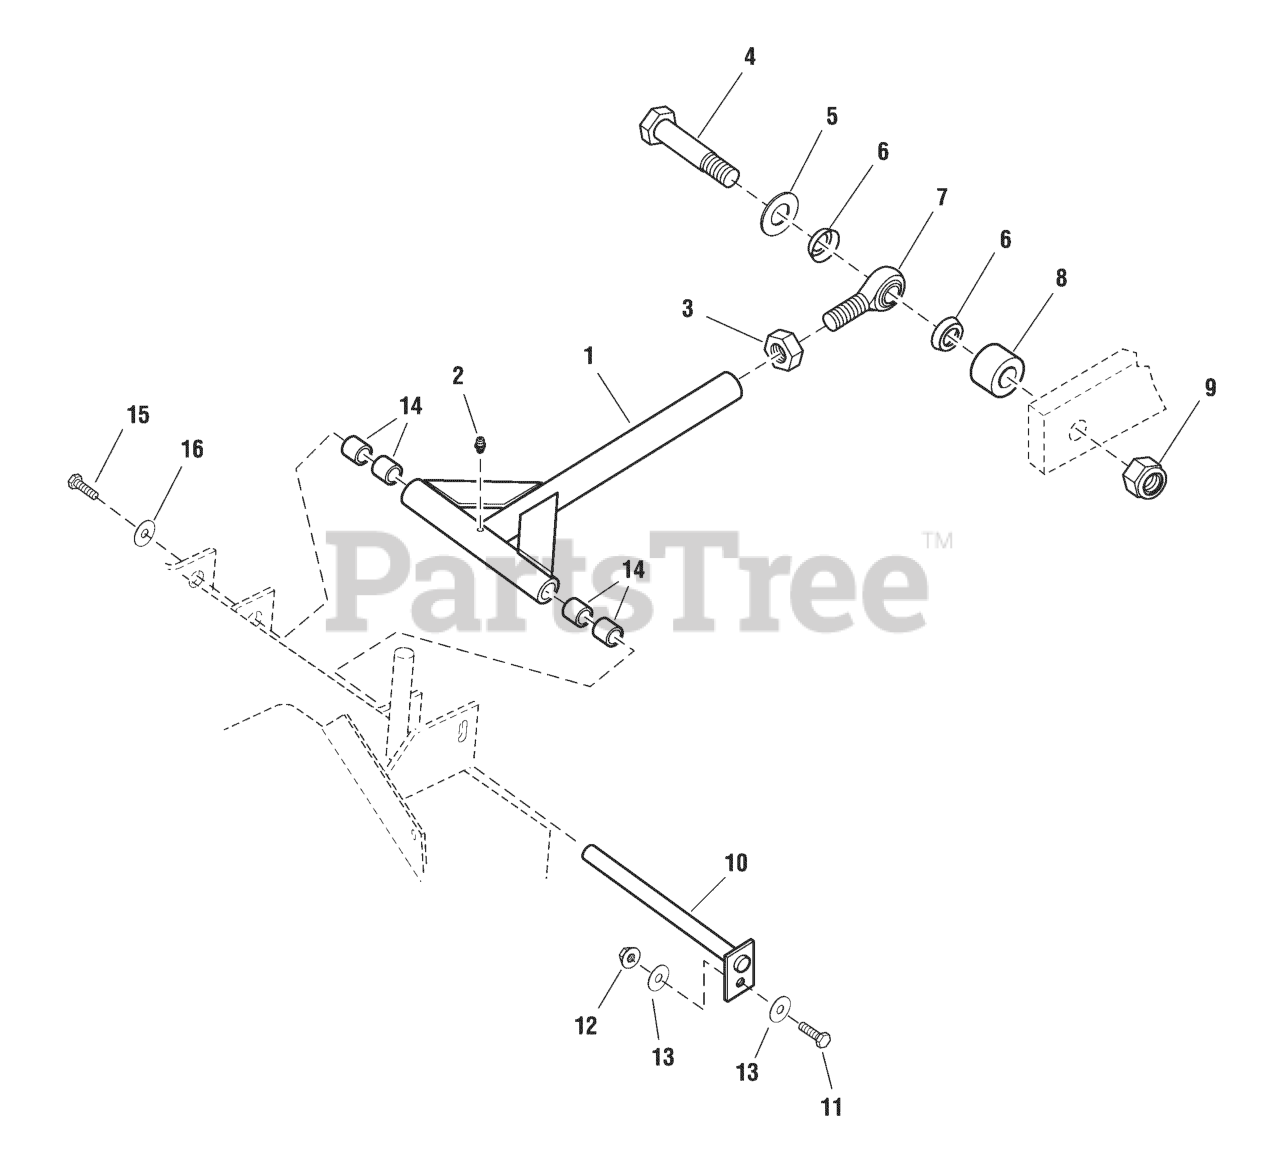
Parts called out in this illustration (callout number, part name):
1	ASSM, DECK PUSHER BAR
2	GREASE FITTING
3	NUT, 3/4-16 Hex Jam
4	BOLT, 3/4-16 x 4
5	WASHER, 3/4 SAE
6	ROD END SEAL
7	BALL JOINT, 3/4-16 Male
8	SPACER, .75 x 1.50 x 1.00
9	NUT, 3/4-16 Hex Nylon Lock
11	BOLT, 3/8-16 X 1-1/4" GD5 CZ
12	NUT, 3/8-16 HEX NYLON LOCK
13	WASHER, 3/8 SAE
14	BUSHING, .75 X 1.00 X 1.00, PLASTIC
15	BOLT, 3/8-16 X 1" GD5 CZ
16	WASHER, .390 X 1.50 X .109 YZ
